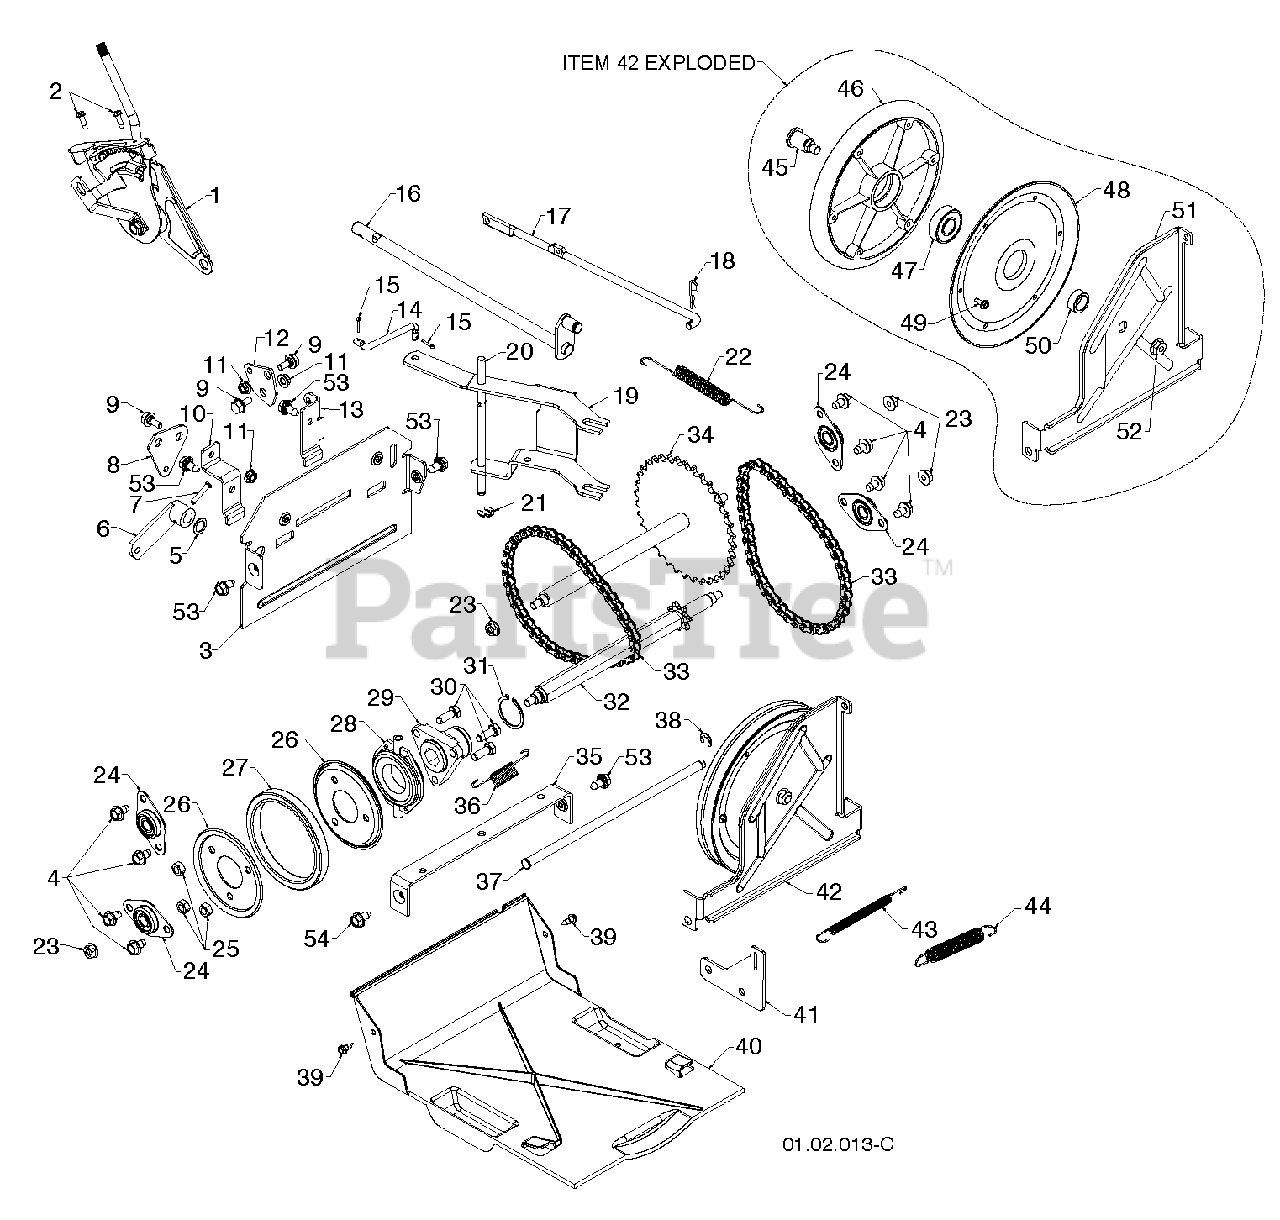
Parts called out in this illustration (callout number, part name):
2	SCREW #10-24 X 5/8
3	PLATE.END.CHAIN.ASM.YELLOW
4	SCREW LT
5	THRUST WASHER
6	ARM, AUGER CONTROL
7	CLEVIS PIN
8	PLATE.SHIFTER.BZP
9	BOLT.SHOULDER.3/X.25
10	Shifter Plate Bracket, Bzp
11	NUT.HEX.FLANGE.1/4
12	Clutch Plate
13	Clutch Bracket Plate
14	LINK, SPEED CONTROL
15	RETAINER CLIP
16	CONTROL.SHAFT.ASM
17	ROD.CLUTCH.SWING.PLATE
18	SPRING RETAINER
19	SHIFTER BRACKET
20	ROD.PIVOT.SHIFTER
21	KLIP RING TI
22	SPRING.TRACTION.RETURN
23	NUT.LOCK.5/16-18
24	BEARING FLANGE BALL
25	NUT.CENTERLOCK.5/16-
26	PLATE.RUBBER.WHEEL
27	RING.RUBBER.2-STG.SNW.DRV.WH
28	TRUNNION BEARING ASSY
29	HUB, RUBBER WHEEL
30	BOLT
31	Retaining Ring
32	SHAFT.HEX.W/SPOCKET
33	CHAIN.DRIVE.SNOWTHROWER.#420
34	SPROCKET.WELDMENT
35	BRACKET.YOKE.SHIFTER.BLACK
36	SPRING, BIAS
37	ROD.PIVOT.SWING.PLATE.SNOW
38	E-RING.RETAINER.REINFORCED.375
39	SCREW, HEX HEAD, TAPPING
40	PAN.BOTTOM.PLASTIC
41	BRACKET.TRACTION.SPRING.
42	RP.PULLEY.PLATE.ASM.DRIVE
43	SPRING.TRACTION.IDLER
44	SPRING, BRAKE
45	SHAFT.FRICTION.PULLEY.SNOW
46	PULLEY.PLATE.ASM.DRIVE
48	PULLEY.HALF.TRACTION
49	SCREW
50	SPACER BEARING
51	SWINGPLATE
52	FLANGED LOCKNUT 3/8-16 ZINC
53	BOLT.HEX.HD.WASHER.5/16-18X.75
54	BOLT.5/16HEX.WHS.HD
